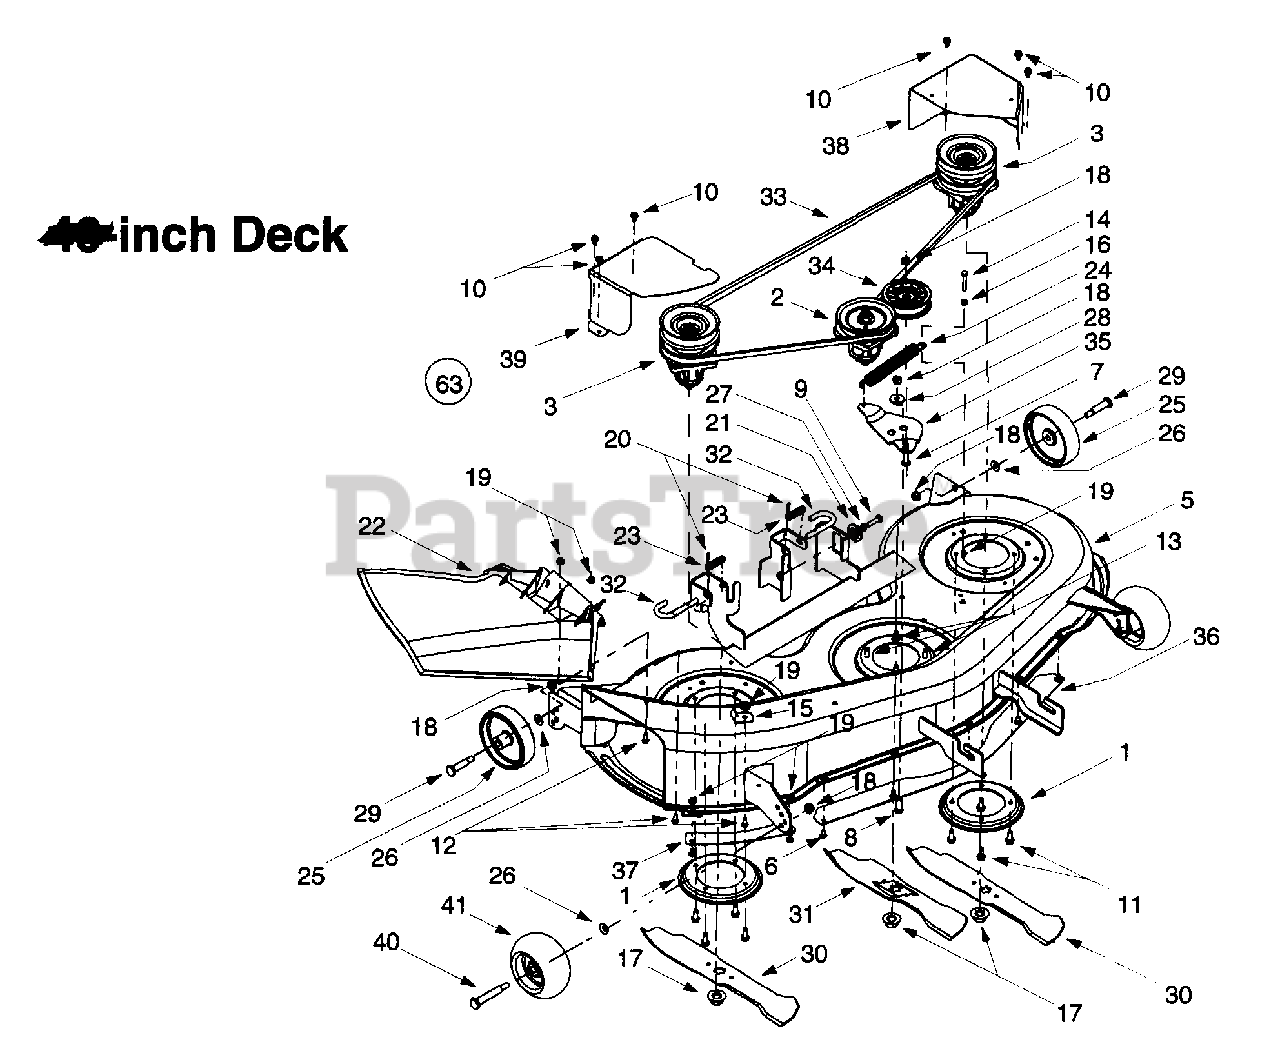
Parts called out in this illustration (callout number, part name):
3	Double Pulley Spindle Assembly
6	Carriage Screw, 1/4-20 x .5
7	Hex Cap Screw, 3/8-16 x 1.75
8	Hex Cap Screw, 3/8-16 x 1.0
9	Hex Cap Screw, 5/16-18 x 1.25
10	Self Tapping Screw,1/4-20 x .5
11	Self Tapping Screw, 5/16-18 x .875
12	Hex Cap Screw, 1/4-20 x .62
13	Self Tapping Screw, 5/16-18 x .75
14	Hex Cap Screw, 1/4-20 x 1.25 (Grade 5)
15	Retainer Hook
16	Center Lock Nut, 1/4-20
17	Hex Flange Nut, 5/8-18
18	Flange Lock Nut, 3/8-16
19	Hex Flange Lock Nut, 1/4-20
20	Internal Cotter Pin, .072 x 1.12
21	Deck Adjustment Gear
22	Side Discharge Chute Assembly
23	Compression Spring, .406 x .531 x 1.75
24	Extension Spring, .91 x 7.33
25	Deck Wheel, 5 x 1.38
26	Bell Washer, .401 x .87 x .063
27	Lock Washer, 5/16
28	Shoulder Spacer, .625 x .169
29	Shoulder Spacer, .498 x 1.53
30	Three-in-one Blade, Star Center, 16.28 46"
31	Three-in-one Blade, Star Center, 14.88 46"
32	Deck Release Pin
33	Deck Belt
34	Flat Idler Pulley, 3.5 OD
41	Deck Wheel, 5
